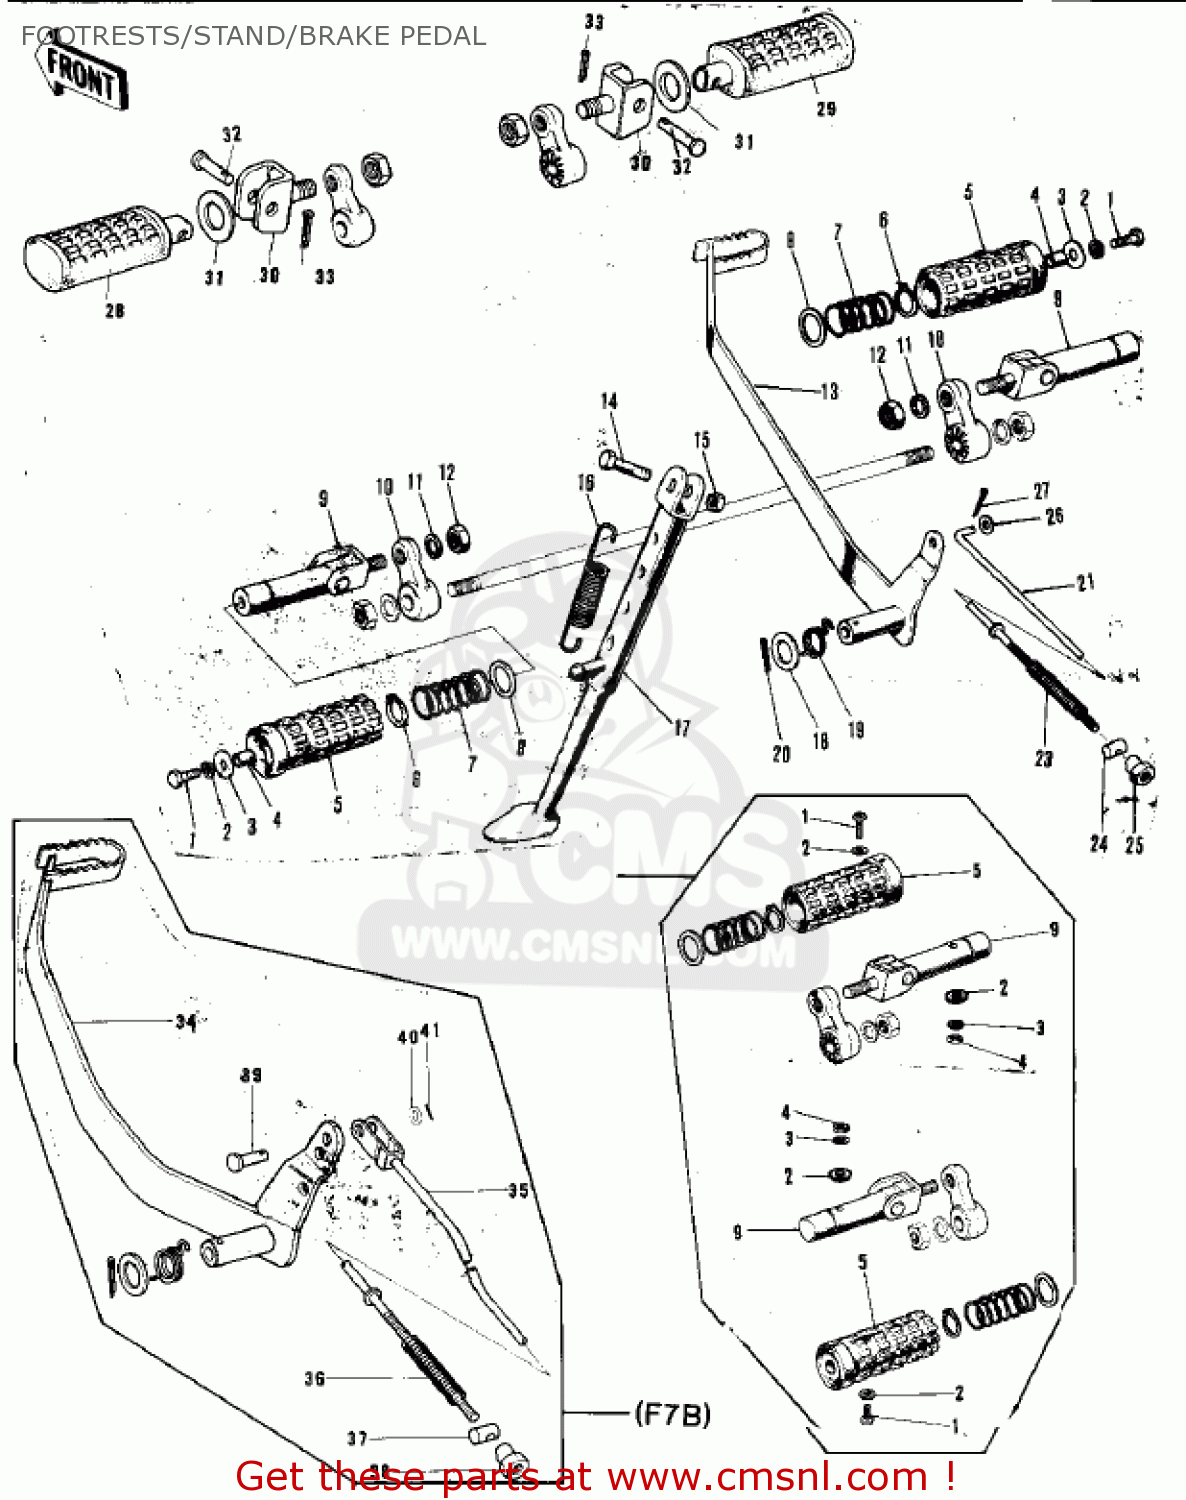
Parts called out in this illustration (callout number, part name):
1	BOLT-UPSET
2	WASHER-SPRING,6MM
3	WASHER,6.5X20X1.6
4	COLLAR
5	RUBBER-FOOTREST
6	CIRCLIP-TYPE-C,16MM
7	SPRING-FOOTREST PEG
8	WASHER-FOLDING PEG
9	BAR-FOOTREST
10	BRACKET-FOOTREST BAR
11	WASHER-SPRING,10MM
12	NUT,10MM
13	PEDAL-BRAKE
14	BOLT,HEX HEAD,10X28
15	NUT,10MM
16	BRAKE ROD ASSY
17	STAND-SIDE
18	WASHER,15.3X24X1.2
19	SPRING,BRAKE PEDAL
20	PIN-COTTER,3.0X30
23	SPRING,BRAKE ROD
24	PIN,BRAKE ROD
25	NUT-BRAKE ROD ADJUST
26	WASHER-PLAIN-SMALL,6M
27	PIN-COTTER,2.0X15
28	STEP-ASSY,FR,LH
29	STEP-ASSY,FR,RH
30	HOLDER-FOOT REST,LH
31	WASHER-PLAIN
32	PIN-FOOTREST BAR FIT
33	PIN COTTER,295X15
34	PEDAL-BRAKE
36	SPRING,BRAKE ROD
37	PIN,BRAKE ROD
38	NUT-BRAKE ROD ADJUST
39	PIN-BRAKE ROD FITTING
40	WASHER-PLAIN-SMALL,6M
41	PIN-COTTER,2.0X15
?	BRAKE ROD ASSEMBLY
